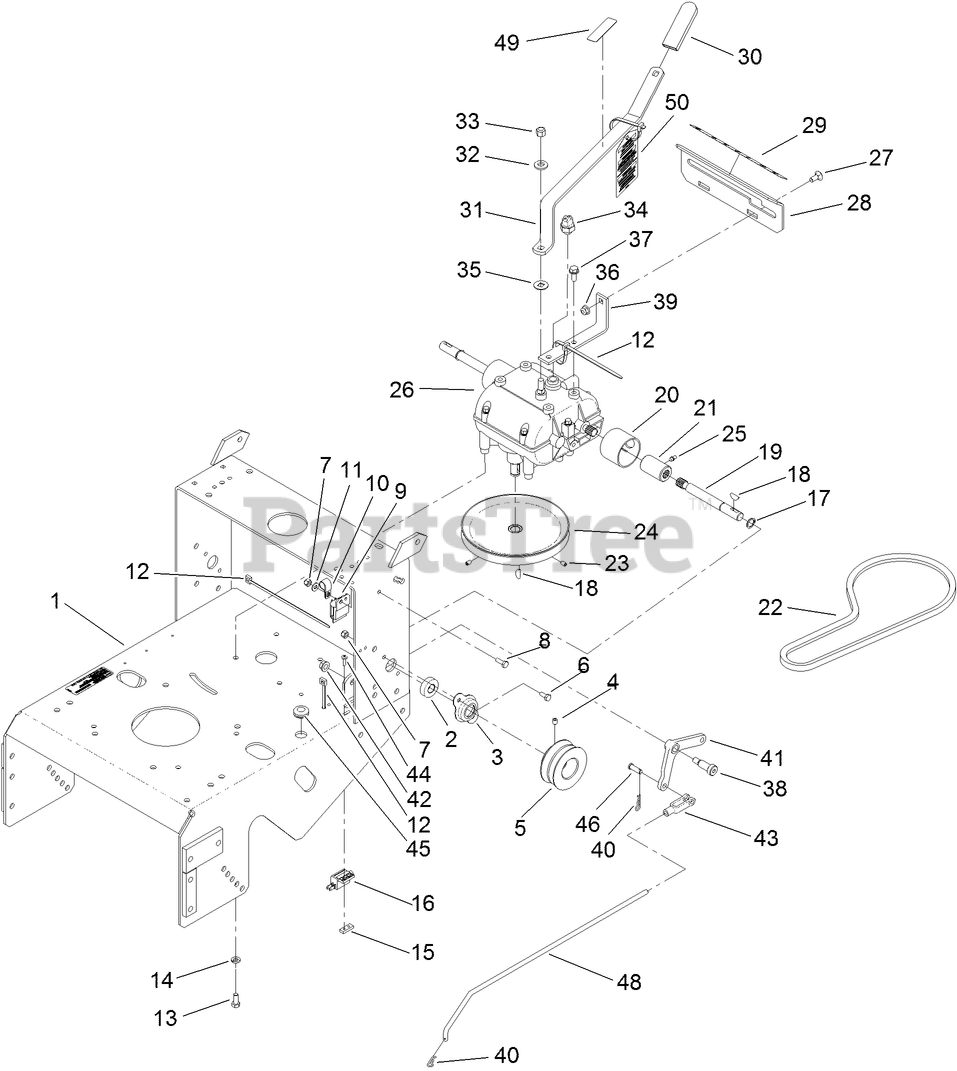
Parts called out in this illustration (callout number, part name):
1	FRAME-GEAR
2	BEARING-SHAFT
3	FLANGE-OUTPUT
4	SETSCREW
5	SHEAVE-TRANSMISSION
6	SCREW-HH
7	NUT-LOCK, NI
8	SCREW-HH
9	MODULE-INTERLOCK
10	CLIP-LOOM
11	WASHER-FLAT
12	TIE-PLASTIC
13	SCREW-HH
14	WASHER-LOCK
15	PLATE-TAPPED
16	SWITCH-OPEN, NORMALLY
17	RING-RETAINING
18	KEY-WOODRUFF
19	SHAFT-TRANSMISSION
20	GUARD-COUPLER
21	COUPLER
22	V-BELT
23	SCREW-HSH
24	SHEAVE-TRANSMISSION
25	FITTING-GREASE
26	TRANSMISSION
27	BOLT-CARR
28	PLATE-SHIFT
29	DECAL-SPEED, GROUND
30	GRIP-LEVER
31	LEVER-SHIFT
32	WASHER-BELLEVILLE
33	NUT-LOCK
34	Switch-Start, Neutral
35	WASHER
36	NUT-HF, NI
37	SCREW-HWHTF
38	BOLT-SHOULDER
39	BRACKET-PLATE, SHIFT
40	PIN-COTTER
41	BELLCRANK
42	NUT-HHF, WHIZ
43	YOKE-ADJUSTABLE
44	SCREW-PPH
45	GROMMET
46	PIN-CLEVIS
48	ARM-ASSIST, LINKAGE
49	DECAL-CAUTION, GEARBOX
50	HANG TAG-GEARBOX
